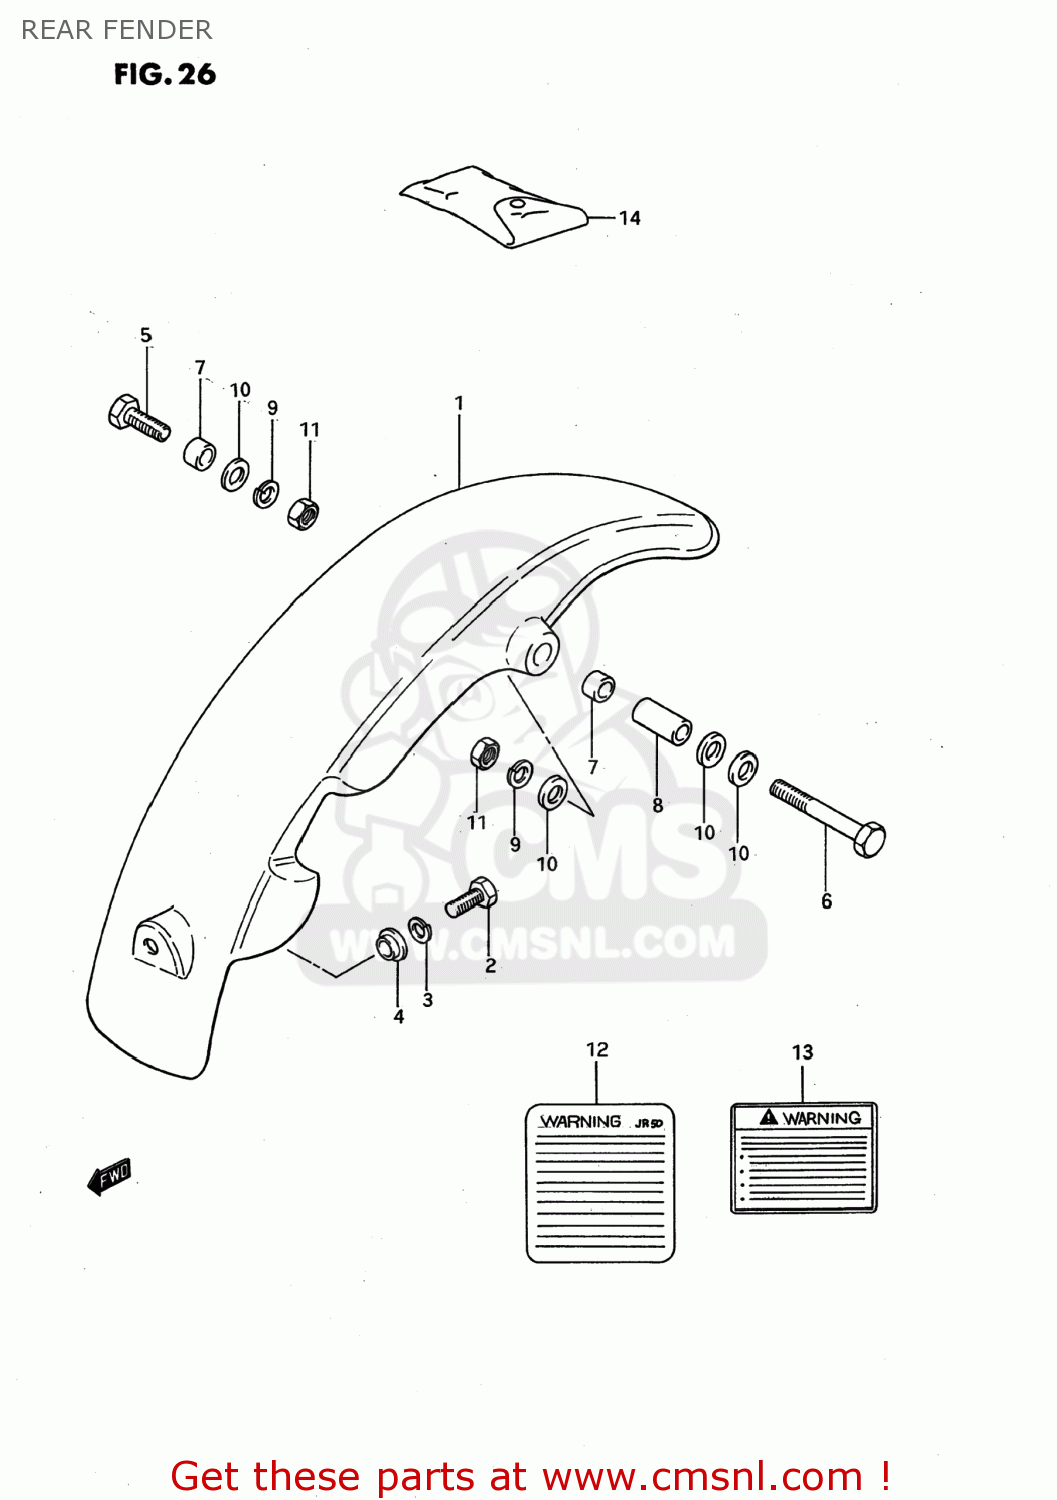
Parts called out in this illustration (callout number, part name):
1	FENDER,RR
2	BOLT
3	WASHER,LOCK
4	WASHER
5	BOLT
6	BOLT, LH
7	SPACER,RR FENDER RR
8	SPACER (8.2X12.5X23.5)
9	LOCK WASHER
10	WASHER
11	NUT
12	LABEL,WARNING
13	LABEL
14	TOOL ASSY
15	MANUAL,OWNER'S
